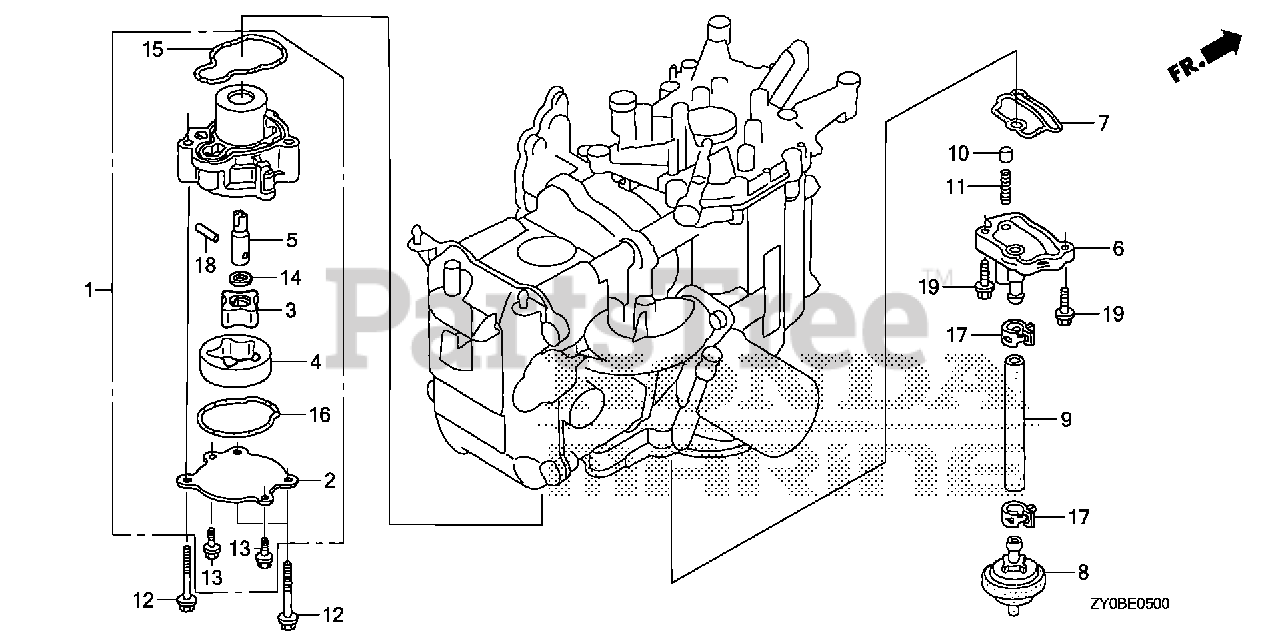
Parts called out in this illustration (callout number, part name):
1	PUMP ASSY., OIL
2	COVER, OIL PUMP
3	ROTOR, OIL PUMP (INNER)
4	ROTOR, OIL PUMP (OUTER)
5	SHAFT, OIL PUMP
6	FLANGE, OIL STRAINER
7	O-RING, OIL STRAINER FLANGE
8	STRAINER, OIL
10	VALVE, CHECK
11	SPRING, CHECK VALVE
12	BOLT, FLANGE (6X35)
13	BOLT, FLANGE (5X12) (CT200)
14	WASHER, THRUST (11MM)
15	O-RING, OIL PUMP
16	O-RING, PUMP COVER
17	CLAMP, TUBE (D17)
18	ROLLER (4X15.8)
19	BOLT, FLANGE (6X22)
